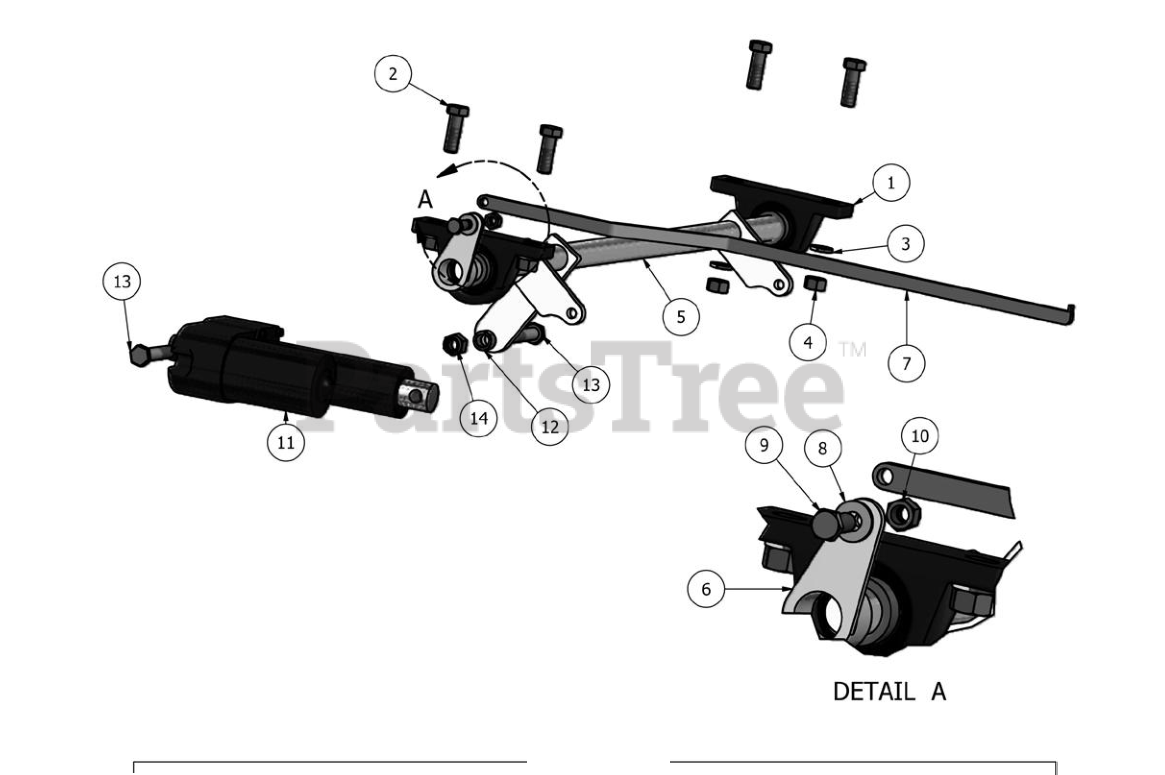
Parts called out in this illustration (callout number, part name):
1	Pillow Block 2Bolt Sealmaster
2	1/2" x 1 1/2" Hex Bolt
3	1/2" Lock Washer
4	1/2" Hex Nut
5	Actuator Bar Diesel
6	Height Indicator Lever
7	Height Indicator
8	.360 ID Plastic Washer
9	3/8" x 1" Hex Bolt
10	3/8 Nylock Nut
12	1/2 x 1/2 Spacer
13	1/2" x 3" Hex Bolt
14	1/2" Nylock Nut
